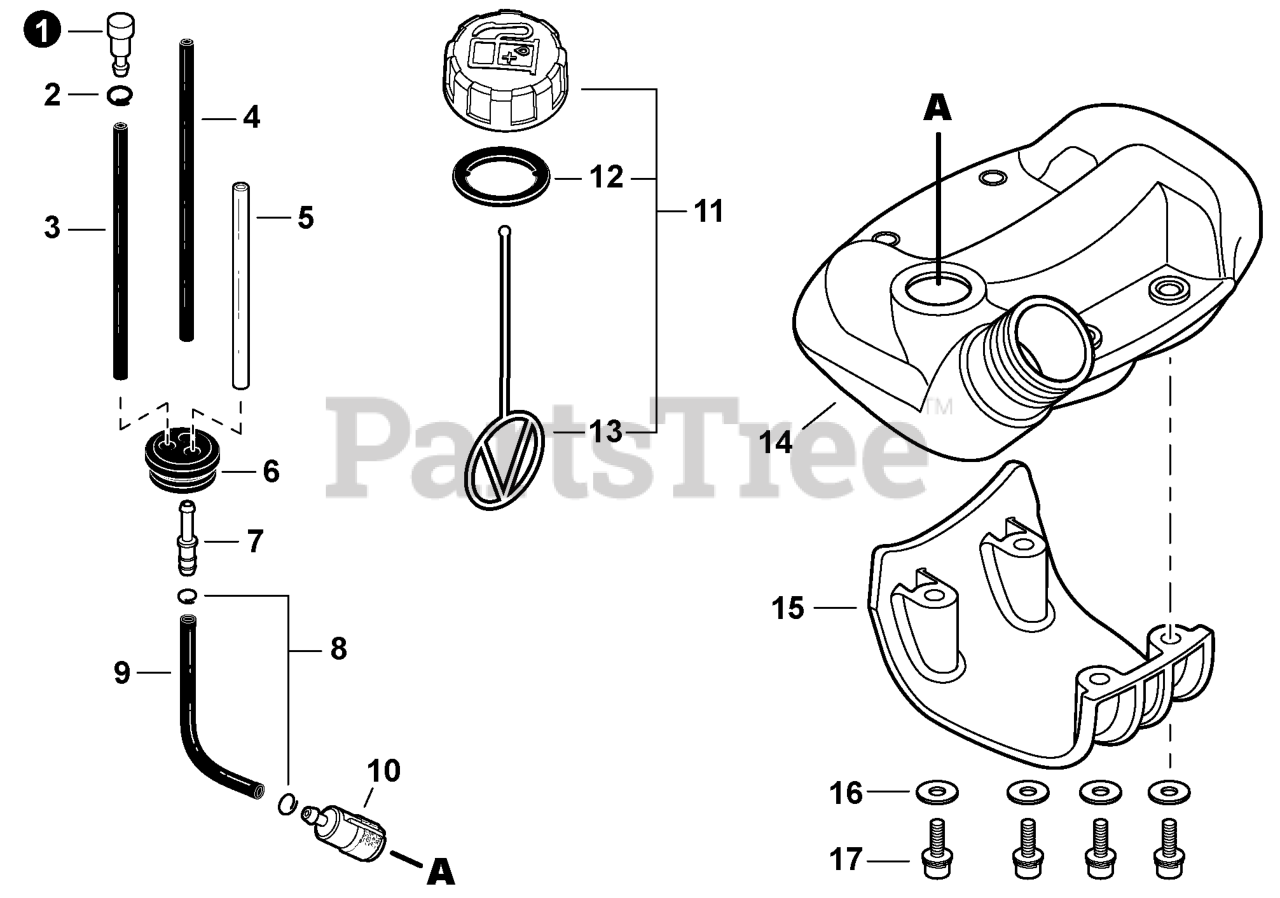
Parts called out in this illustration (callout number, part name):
1	VENT ASSY
2	CLIP 6.5 MM
3	PIPE, FUEL 3x6x35 BLACK
4	PIPE, FUEL 3x5.5x67 BLACK
5	PIPE, FUEL 3x6x75 CLEAR
6	GROMMET, FUEL
7	CONNECTOR, PIPE 5x3.5
9	PIPE, FUEL - 3x5x125 - BLACK
10	FILTER, FUEL
11	CAP ASSY, FUEL
12	GASKET, FUEL CAP
13	CONNECTOR, CAP L= 123
14	TANK, FUEL
15	GUARD, FUEL TANK
16	WASHER 5.5x12x0.8
17	BOLT 5x25
